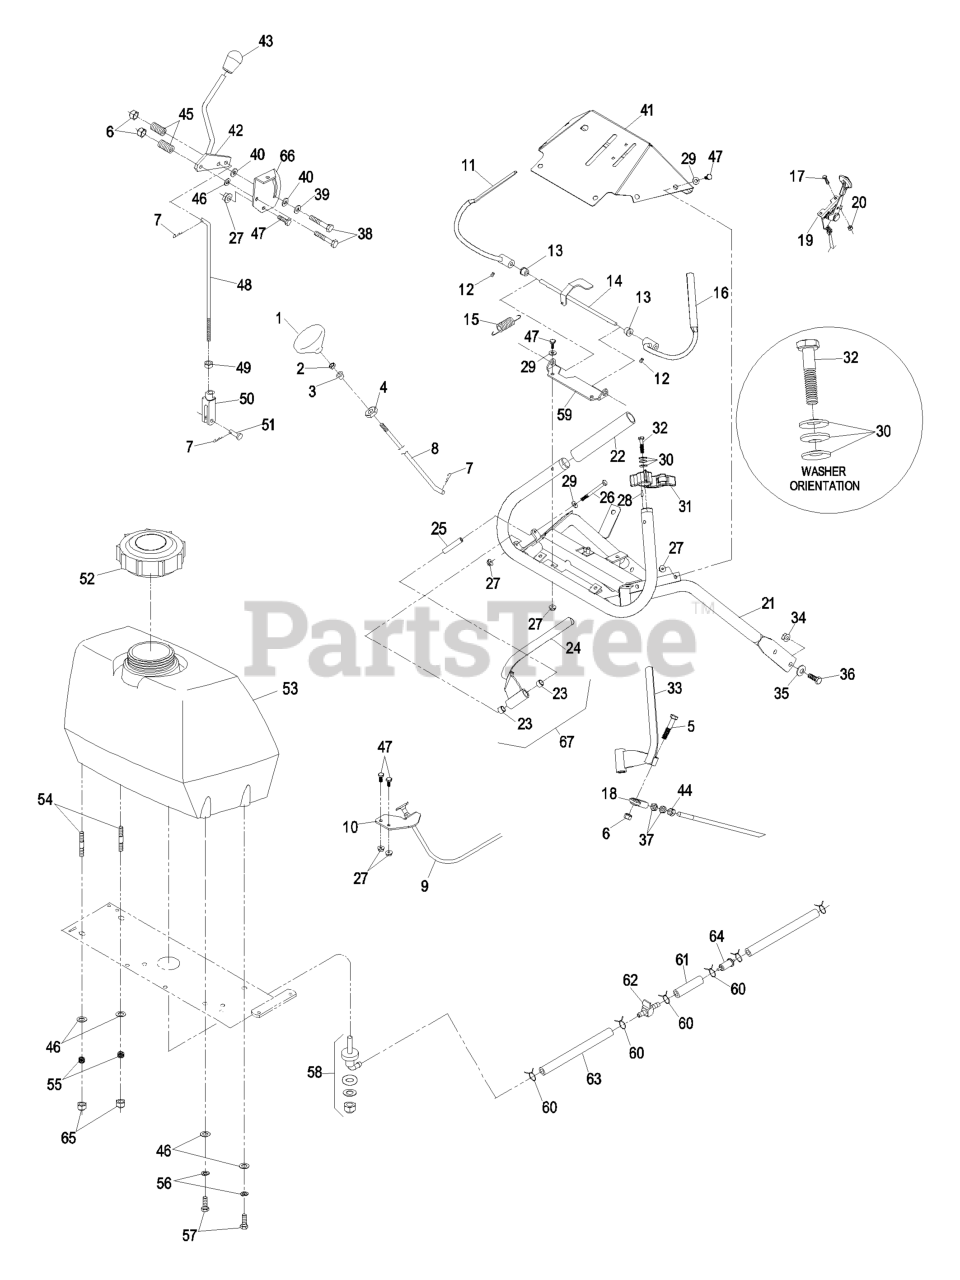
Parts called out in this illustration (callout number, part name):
1	KNOB-PUSH / PULL
2	NUT-JAM
3	BEARING-NYLON
4	NUT-PUSH
5	SCREW-HH
6	NUT-LOCK, NI
7	PIN-COTTER
8	LINKAGE,BLADE PUSH/PULL
9	CABLE-CHOKE
10	BRACKET-CABLE, CHOKE
12	SCREW-SET
13	BUSHING-NYLON
14	WLD,OPC LEVER AXLE
15	SPRING-EXTENSION
17	BOLT-CARR
18	JOINT-BALL, END
19	CONTROL-THROTTLE
20	NUT-LOCK, NI
21	WLD,VH ECS HANDLE
22	GRIP-BAR, HANDLE
23	BUSHING-SLEEVE
25	BUSHING-LEVER, DRIVE
26	SCREW-HH
29	WASHER-FLAT
30	WASHER-SPRING
31	ASM,LATCH RH THUMB
32	SCREW-HH
34	NUT-HHF, WHIZ
35	WASHER-BELLEVILLE
36	SCREW-HH
37	NUT-HJ
38	SCREW-HH
39	WASHER-FRICTION
40	WASHER-FRICTION
41	ASM,CONSOLE W/DECALS
43	KNOB, FE.LCKG. BLACK
44	NUT-HEX
45	SPRING-COMPRESSION
46	WASHER-PLAIN
47	SCREW-HH
48	ROD-CONTROL, SPEED
49	NUT-JAM
50	YOKE-ADJUSTABLE
51	PIN-CLEVIS
52	CAP-FUEL, GAS
53	ASM,FUEL TANK W/B
54	STUD
55	SPRING-TANK, FUEL
56	WASHER-LOCK
57	SCREW-HH
58	FITTING-FUEL, BULKHEAD
59	BRACKET,OPC AXLE
61	HOSE-FUEL
62	VALVE-FUEL
63	HOSE-FUEL
64	Kawasaki Pn 41019-1055 Filter W/6" Fuel Line
65	NUT-LOCK, NI
66	BRACKET,SHIFTER SLIDE (PL
67	DRIVE LEVER-ASM, RH
